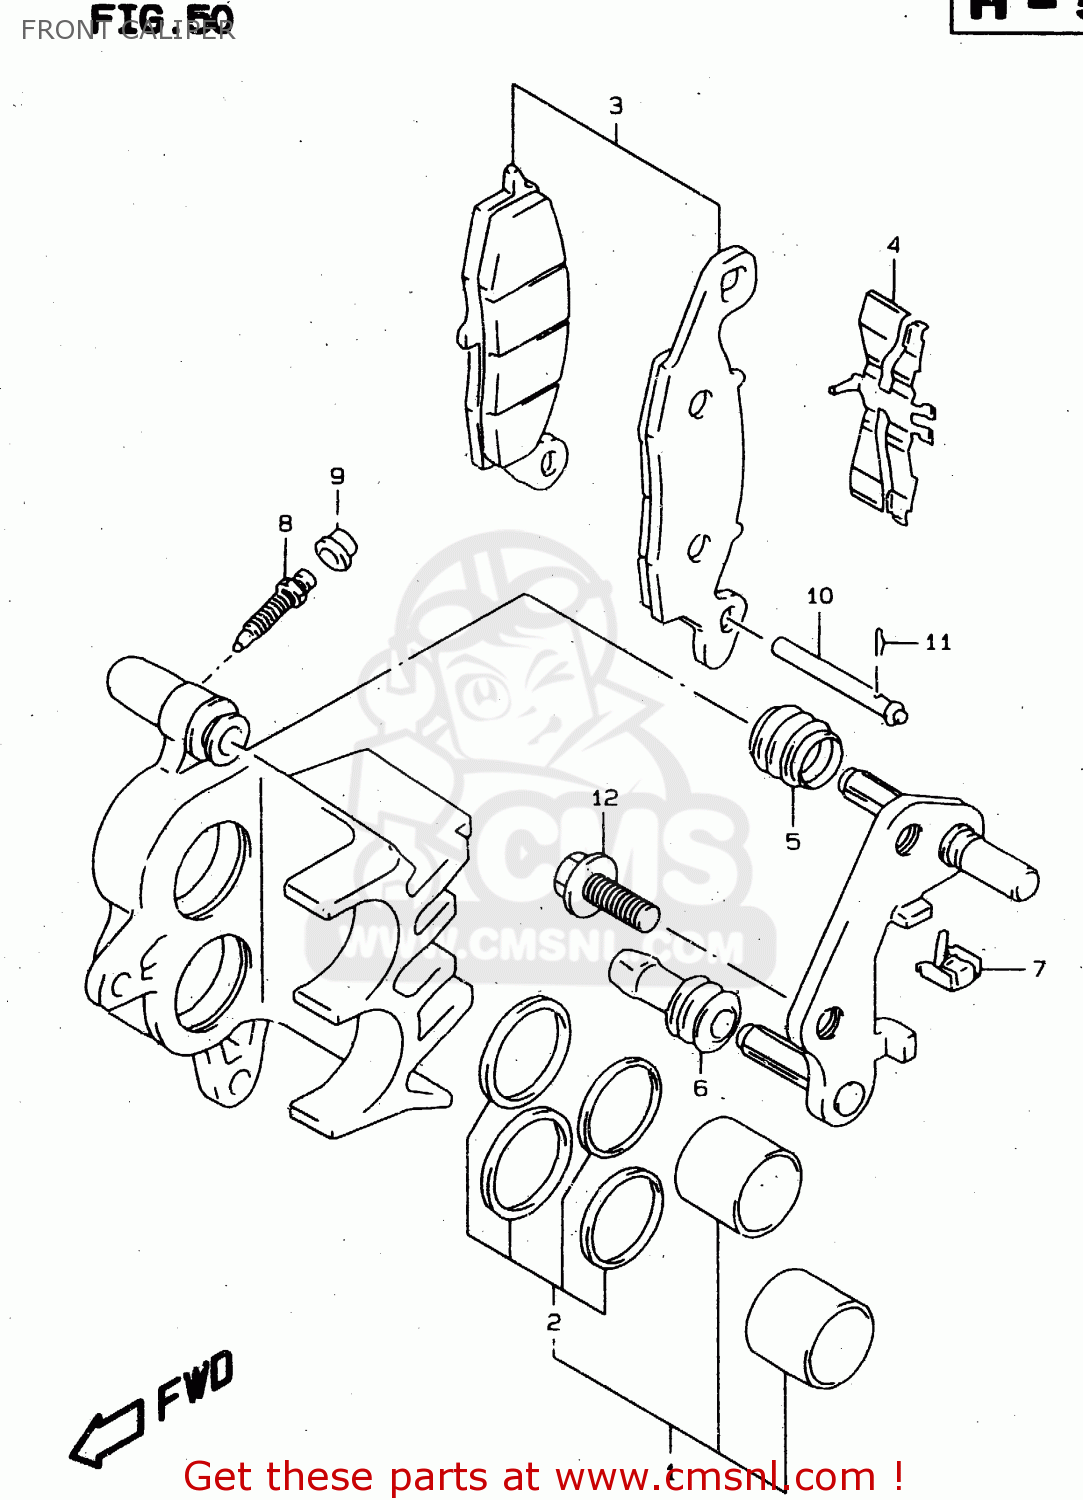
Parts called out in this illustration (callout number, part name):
1	PISTON SET
2	SEAL SET,PISTON
3	PAD SET (NAS)
4	SPRING,PAD,R
5	BOOT,AXLE
6	INSULATOR,AXLE
7	GUIDE,PAD
8	BLEEDER
9	CAP,BLEEDER PLUG
10	PIN,PAD
11	CLIP,PAD PIN
12	BOLT
